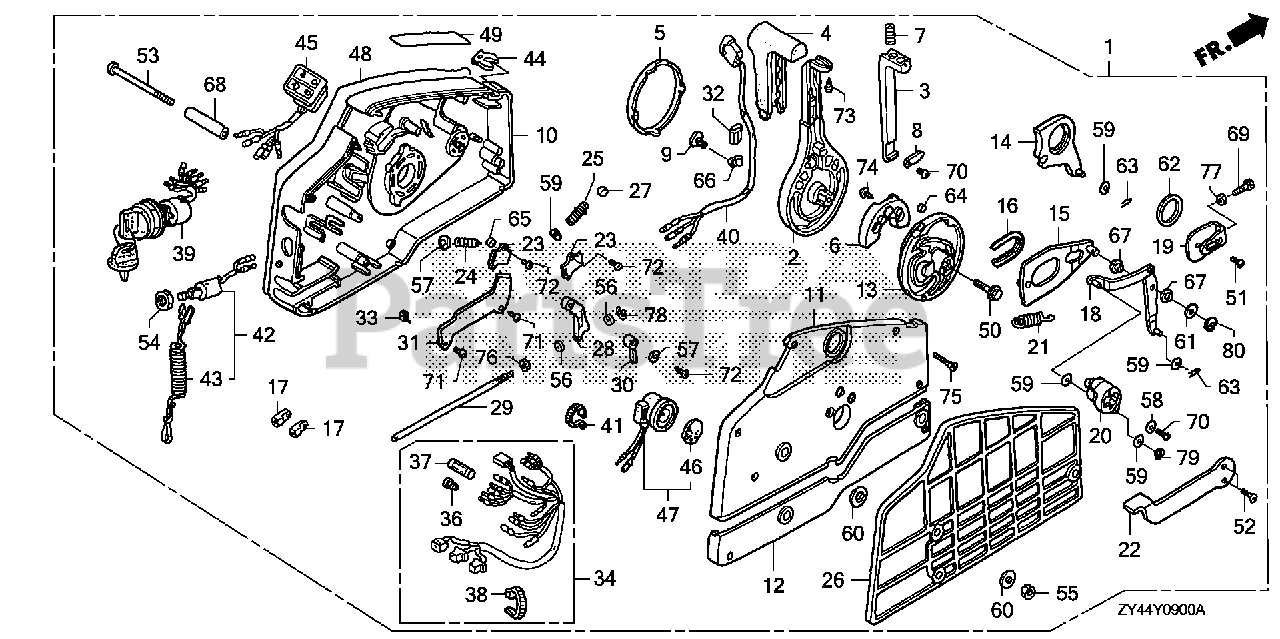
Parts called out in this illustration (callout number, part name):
1	BOX ASSY., REMOTE CONTROL (NHK MEC)
1	BOX ASSY., REMOTE CONTROL (TROLLING CONTROL)(NHK MEC)
2	HANDLE, REMOTE CONTROL
3	LEVER, HANDLE LOCK
4	GRIP, REMOTE CONTROL HANDLE
5	CAP, HANDLE
6	BLOCK, NEUTRAL LOCK
7	SPRING, REMOTE CONTROL HANDLE
8	PLATE, LEVER SETTING
9	CLAMP, HARNESS
10	HOUSING, REMOTE CONTROL BOX (A)
11	HOUSING, REMOTE CONTROL BOX (B)
12	HOUSING, REMOTE CONTROL BOX (C)
13	WHEEL, CONTROL
14	ARM, SHIFT LINK
15	PLATE, SLIDING
16	COLLAR, SLIDING PLATE
17	PIVOT, SHIFT
18	ARM, LINK JOINT
19	BRACKET, LINK JOINT
20	WHEEL, ACCELERATOR
21	SPRING, ACCELERATOR WHEEL
22	LEVER, IDLE
23	PLATE, SPRING SETTING
24	SPRING, SHIFT CLICK
25	SPRING, CHOKE RETURN
26	SPACER, REMOTE CONTROL BOX
27	SPACER, CLICK SPRING
28	BLOCK, THROTTLE FRICTION
29	BOLT, FRICTION
30	SPACER, NEUTRAL SWITCH
31	CLAMP, POWER TILT CORD
32	PIPE, HARNESS GUIDE
33	SPACER, CABLE CLAMP
34	CABLE ASSY., REMOTE CONTROL (B)
36	PLUG, CONNECTOR (INNER)
37	PLUG, CONNECTOR (OUTER)
38	TIE, CABLE (2.4X92) (NATURAL)
39	SWITCH ASSY., COMBINATION
40	SWITCH ASSY., POWER TRIM-TILT
41	BAND (BLACK 3.5X140)
42	SWITCH ASSY., EMERGENCY STOP
43	WIRE, EMERGENCY
44	CLIP, EMERGENCY LOCK
45	LAMP ASSY., INDICATION
46	PLATE, TURN SIGNAL BUZZER
47	BUZZER, WARNING
48	PLATE, REMOTE CONTROL (COUTION COLOR=RED & YELLOW)
49	MARK, FAST IDLE
50	BOLT, FLANGE (8X35)
51	SCREW, PAN (6X10)
52	SCREW, FLAT (5X12)
53	SCREW (6X95)
54	NUT, HEX. (16MM)
55	NUT, HEX. (6MM)
56	WASHER, PLAIN (4MM)
57	WASHER, PLAIN (5MM)
58	WASHER, PLAIN (5MM)
59	WASHER, PLAIN (6MM)
60	WASHER (6MM)
61	WASHER, PLAIN (8MM)
62	WASHER (28MM)
63	PIN, LOCK (6MM)
64	PIN (6X6)
65	ROLLER, CLICK
66	CLIP, WIRE HARNESS (6.3MM)
67	COLLAR, LINK JOINT
68	COLLAR, DISTANCE (6X10X43.5)
69	BOLT, HEX. (5X16)
70	SCREW, PAN (5X10)
71	SCREW, TAPPING (5X8)
72	SCREW, TAPPING (5X10)
73	SCREW, TAPPING (5X12)
74	SCREW, TAPPING (6X16)
75	SCREW, TAPPING (5X25)
76	NUT, HEX. (6MM)
77	NUT, HEX. (5MM)
78	E-RING (3MM)
79	E-RING (4MM)
80	E-RING (7MM)
